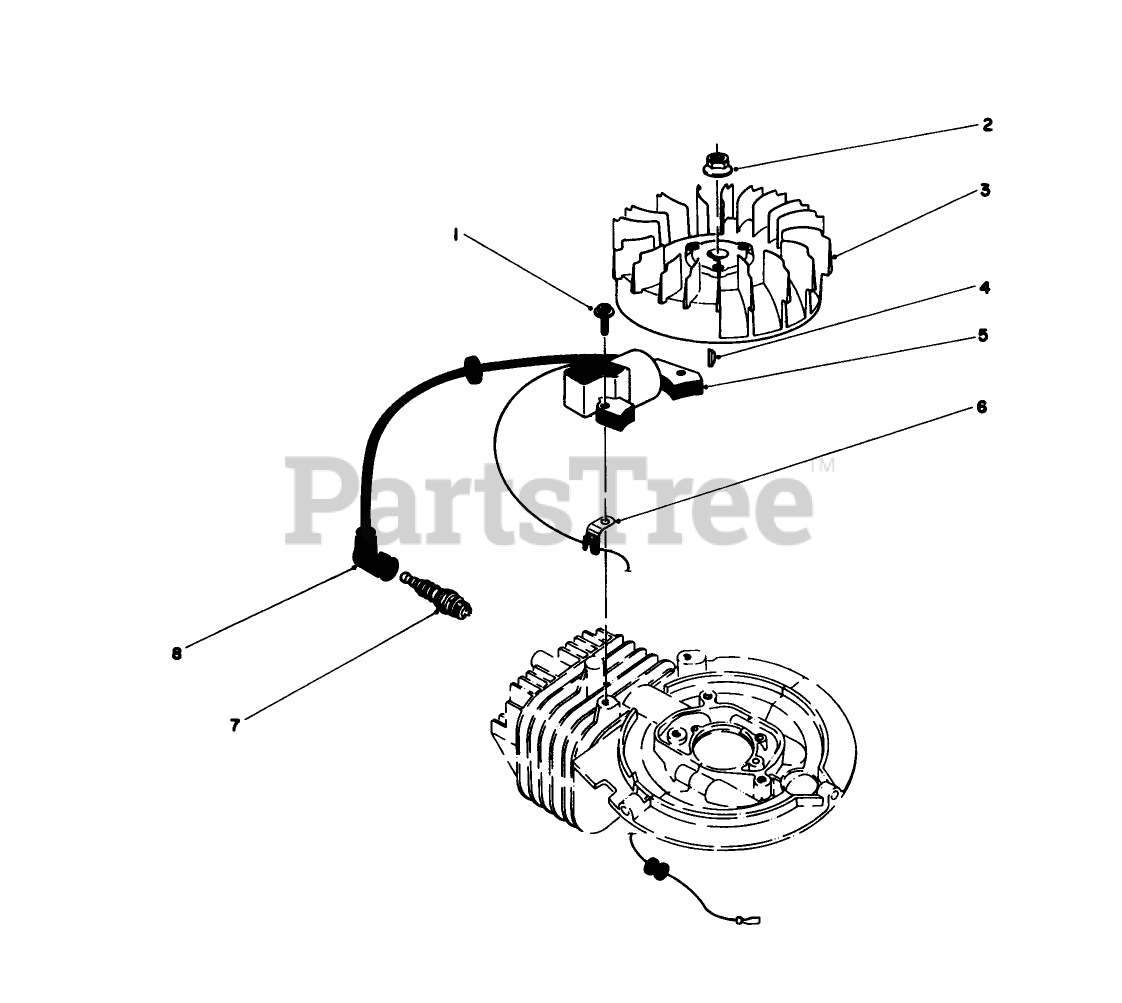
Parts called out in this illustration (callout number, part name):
1	Allenhead
3	FLYWHEEL
5	Coil/Ignition Assembly
6	CLAMP
7	Sparkplug
8	CAP-SPARKPLUG
